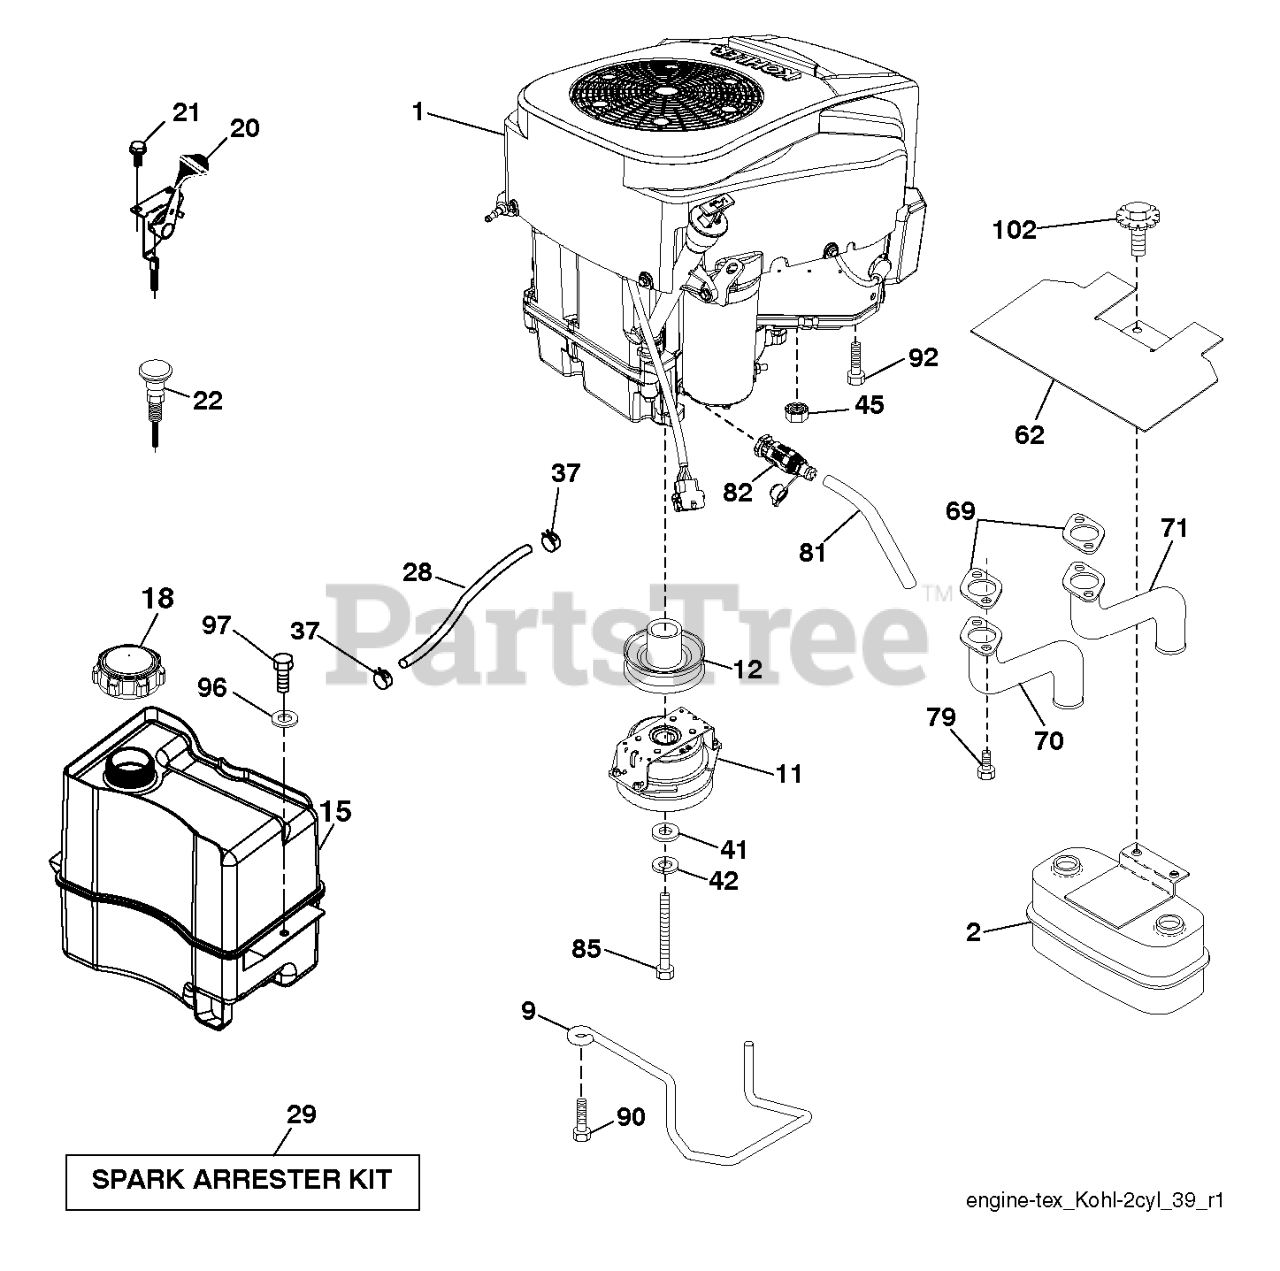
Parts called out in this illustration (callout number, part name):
2	MUFFLER.ASM.TWN.EXTNDED.DFLCTR
9	KEEPER BELT ENGINE
11	CLUTCH.OGURA.5.0PD.GT1.5A-EH07
12	PULLEY.ENGINE.TUFFTORQ
15	TANK.ASSEMBL.2.5GAL.NON-EPA
18	CAP ASM.FUEL.2.25"FR.
20	THROTTLE CONTROL
21	SCREW.#10 X 0.750.BOS
22	CONTROL.CHOKE.ERGO.PUSH-IN.BLA
28	LINE.FUEL.64"REAR.EMIS
29	KIT.SPARK ARRESTOR 794945 B&S
37	HOSE CLAMP
42	LOCKWASHER
45	NUT
62	SHIELD.HEAT.MUFFLER
69	GASKET.EXHAUST.KOHL.CV18-CV26
70	PIPE.EXHAUST.LH.CV18/20
71	PIPE.EXHAUST.RH.CV18/20
79	SCREW.SOCKET HD.5/16-1
81	TUBE, DRAIN OIL ASM.
82	VALUE.OIL.DRAIN
85	BOLT HEX 7/16-20 X 3.75 GR. 5
90	SCREW 3/8-16X1
92	SCREW 3/8-16X1
97	SCREW HEXWSHR 1/4-20X3/4
102	SCREW
